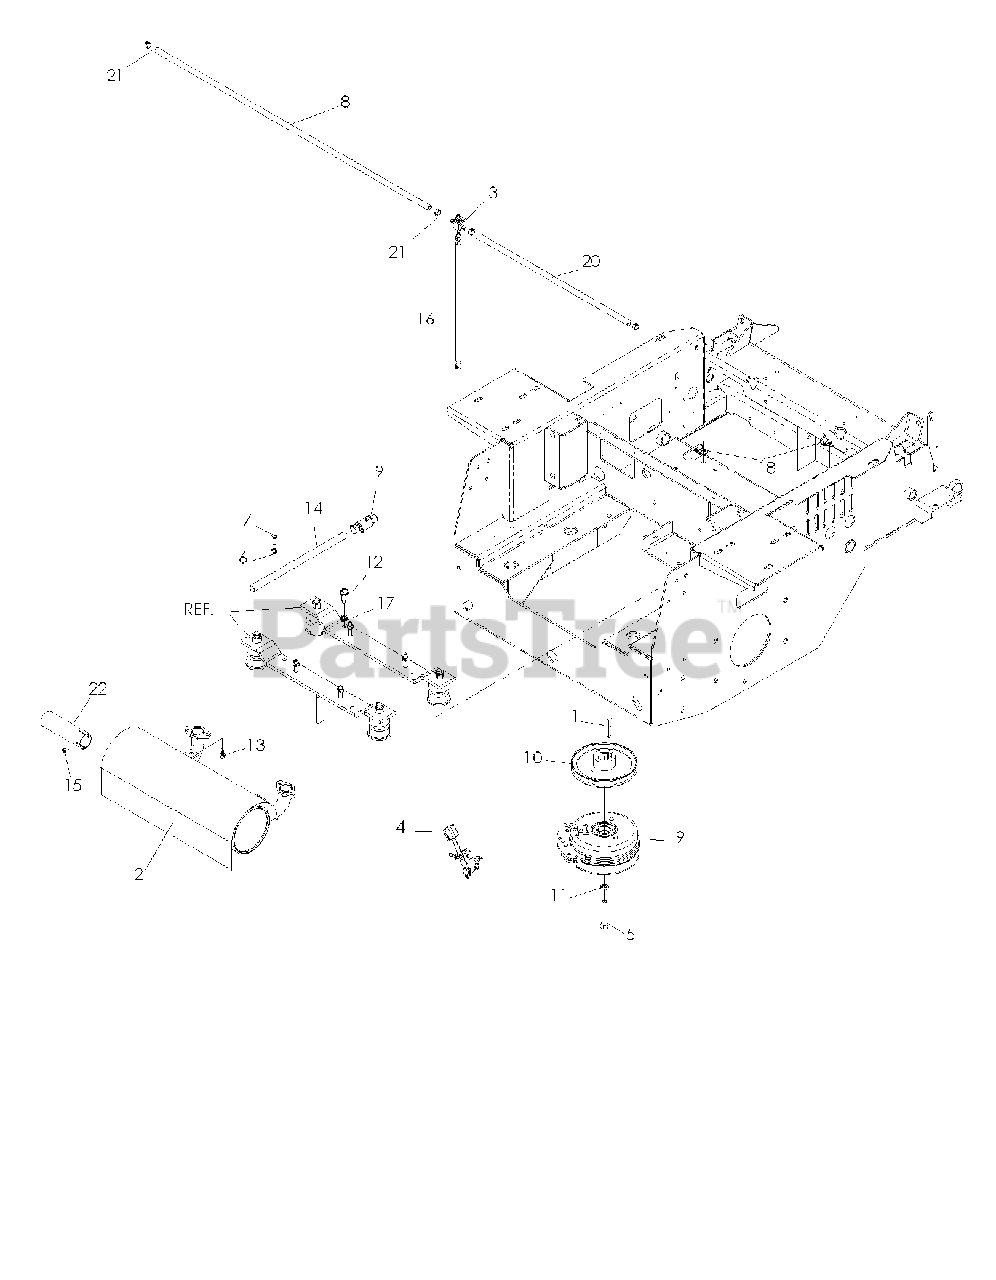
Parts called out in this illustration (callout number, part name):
1	KEY 1/4" SQ X 1 7/8"
2	MUFFLER
3	FUEL VALVE
4	CHOKE CABLE
5	BOLT 7/16F X 2 1/2
6	NUT 1/4C CENTER LOCK
7	HCS 1/4C X 3/4 HCS
8	HOSE 35"
9	ELECTRIC CLUTCH W/CABLE
11	WASHER 7/16 LOCK
12	BOLT 3/8-16 X 1.0
13	SCREW- 1/4-20 X 5/8
14	OIL DRAIN HOSE
15	SCR #8 X 1/2 PHIL HD DRILL BLK
16	FUEL LINE 13"
17	WASHER 3/8 EXT STAR ZD
18	DOUBLE TUBE CLAMP
19	OIL DRAIN FITTING
20	FUEL LINE
21	HOSE CLAMP
22	TUBE, EXTENSION, MUFFLER
